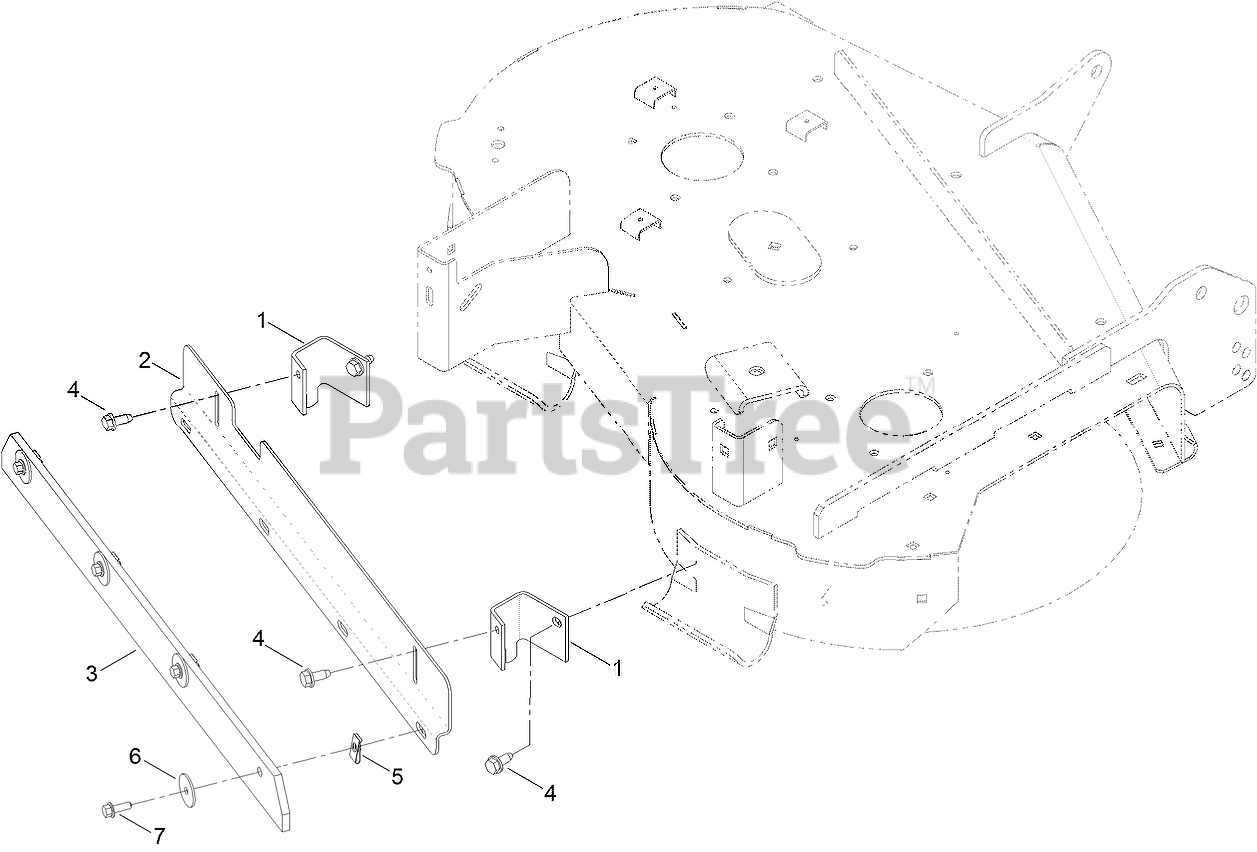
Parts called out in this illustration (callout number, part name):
2	BRACKET-STRIPING, 34" FAB
3	WIPER-34"
4	SCREW-HWHTF
5	NUT-SPEED
6	WASHER-FLAT
7	SCREW-HHF
